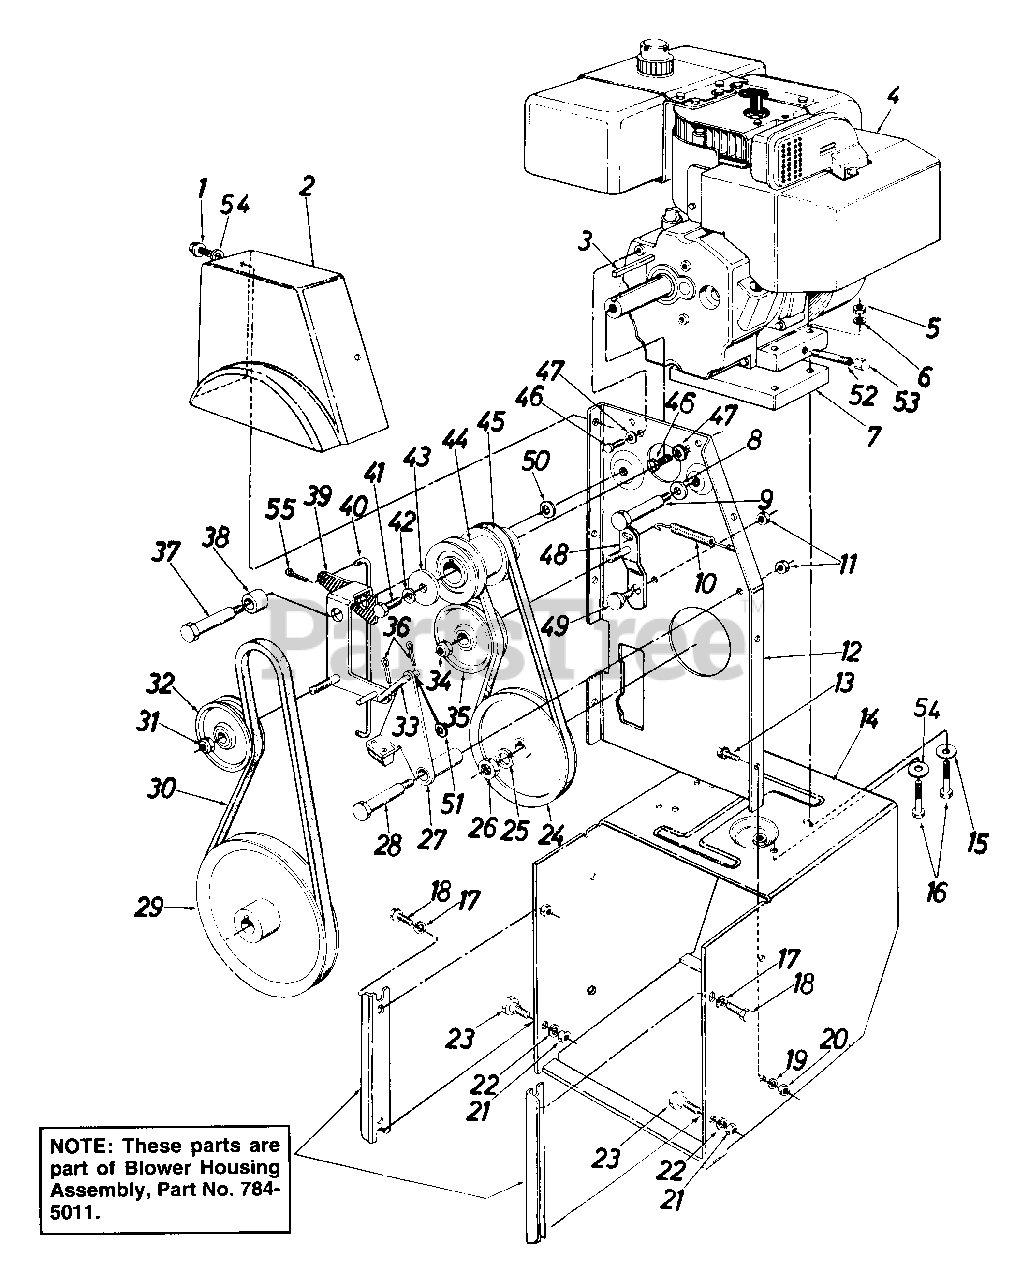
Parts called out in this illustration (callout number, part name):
1	Hex AB-Tap Scr. 5/16 x .75" Lg.
2	Belt Cover
3	Sq. Key 1/4" x 1.50" Lg.
4	Engine
5	Hex Nut 5/16-18 Thd.
6	L-Wash. 5/16" I.D.
7	Engine Spacer Ass'y.
8	Bell-Wash. .40 I.D. x.88 O.D.
9	Shld. Bolt .498" Dia. x 3.00" Lg.
10	Ext. Spring .38 O.D. x 3.18" Lg.
11	Hex Cent. L-Nut 3/8-16 Thd.
12	Engine Brkt. Ass'y.
13	Hex Sems Scr. 5/16-18 x .75" Lg.
14	Frame Ass'y.
15	Fl-Wash. .344" I.D. x 1.125" O.D. x .12"
16	Hex Bolt 5/16-18 x 2.25" Lg.
17	L-Wash. 3/8" I.D. H.D.
18	Pilot Scr. 3/8-16 x .88" Lg.
19	L-Wash. 5/16" I.D.
20	Hex Nut 5/16-18 Thd.
21	Hex Nut 3/8-16 Thd.
22	L-Wash. 3/8" I.D. H.D.
23	Shld. Bolt .498" Dia. x .340" Lg.
24	V-Pulley .628 I.D. x 7.50 O.D.
25	L-Wash. for 5/8" I.D.
26	Hex Ins. Jam L-Nut 5/8-18 Thd.
27	Brake Brkt. Ass'y.
28	Shld. Bolt .498" Dia. x 2.00" Lg.
29	V-Pulley .875 I.D. x 10.12 O.D.
30	"V"-Belt
31	Hex Ins. Jam L-Nut 3/8-24 Thd.
32	Fl-Idler w/Flanges 3.0 O.D.
33	Brake Linkage Ass'y.
34	Hex Ins. Jam L-Nut 3/8-24 Thd.
35	3.0" O.D. Fl-Idler w/Flanges
36	Int. Cot. Pin 3/32" Dia.
37	Shld. Bolt .625" Dia x 2.750" Lg.
38	Spacer .75 O.D. x 1.00" Lg.
41	Hex Bolt 3/8-24 x 1.25" Lg.
42	L-Wash. 3/8" I.D. H.D.
43	Fl-Wash.
44	Engine Pulley - Double Groove
45	"V"-Belt
46	Hex Bolt 5/16-24 x .62" Lg.
47	Bell-Wash. .345 I.D. x .88 O.D. x .060
48	Drive Idler Brkt. Ass'y.
49	Shld. Bolt - .625" Dia. x .170" Lg.
50	Bell-Wash. .40 I.D. x 1.12 O.D.
51	Fl-Wash. .385" I.D. x .620" O.D.
52	Pipe Nipple - 1/4" Pipe Thd. x 3.5" Lg.
53	Hex Hd. Cap 1/4-18 Pipe Thd.
54	Fl-Wash. .344" I.D. x .62" O.D. x .63"
55	Int. Cot. Pin 5/16" Dia.
